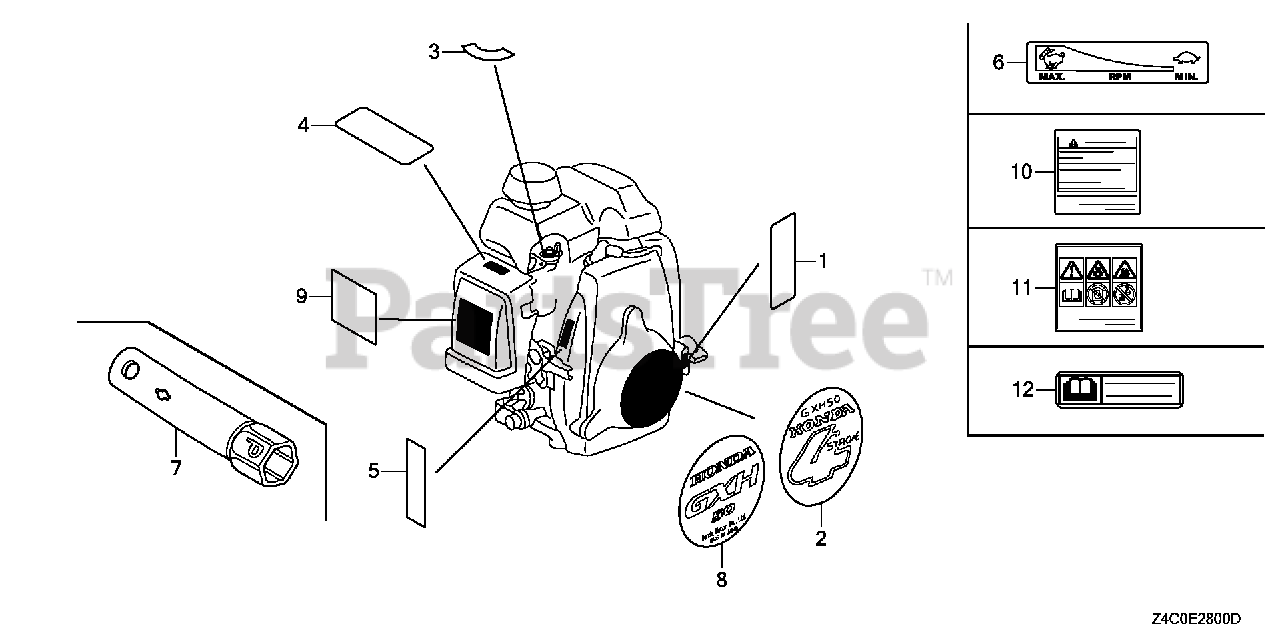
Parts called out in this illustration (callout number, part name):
2	EMBLEM (4STROKE)
2	EMBLEM (GXH50)
3	MARK, PETCOCK (EXTERNAL)
5	MARK, THROTTLE INDICATION
7	WRENCH, SPARK PLUG
8	EMBLEM (GXH50)
9	MARK, OPERATOR CAUTION (PICTOGRAPH)
10	MARK, OPERATOR CAUTION (ENGLISH)
10	MARK, OPERATOR CAUTION (FRENCH)
